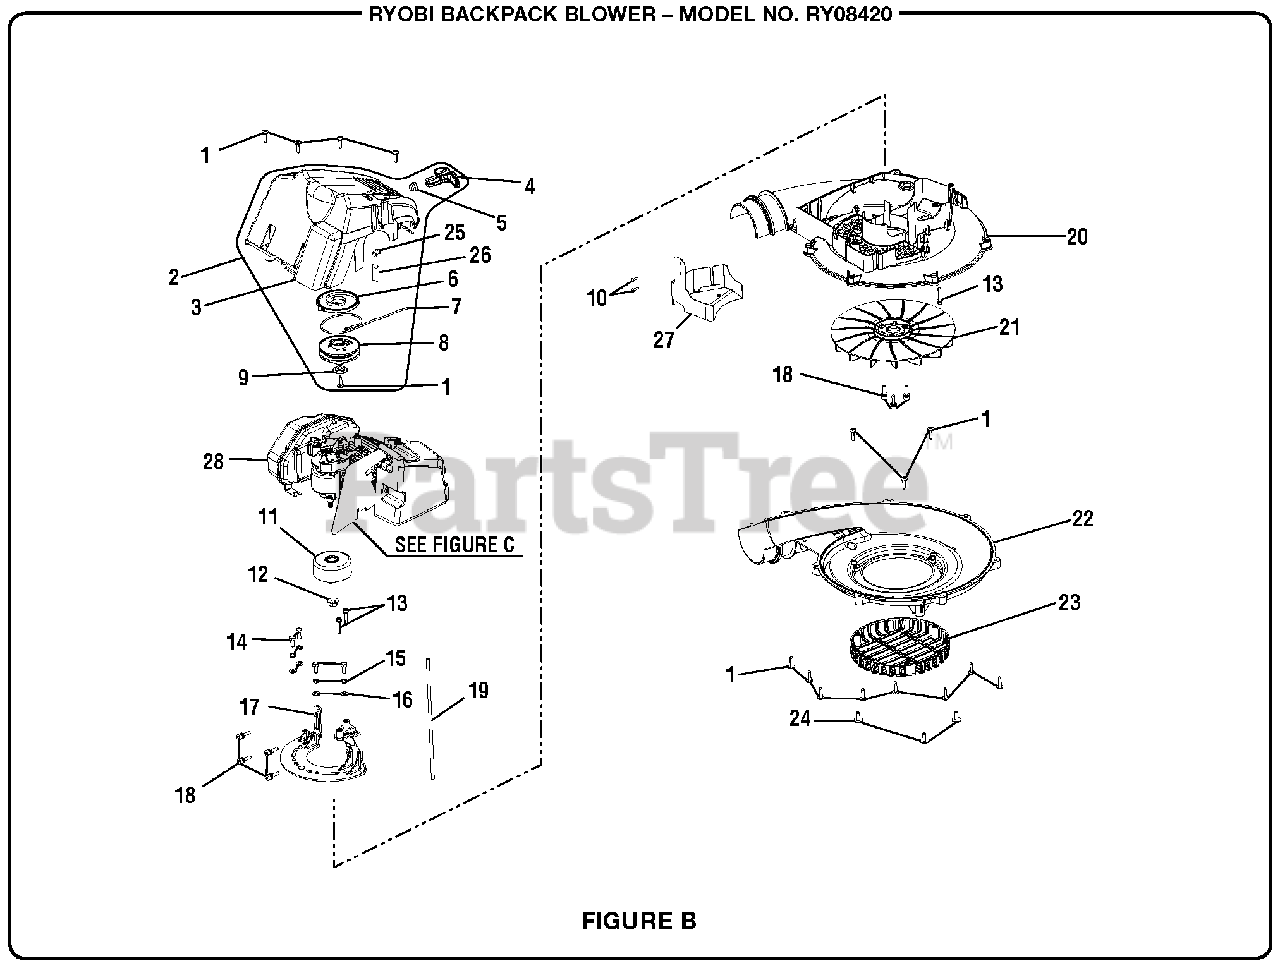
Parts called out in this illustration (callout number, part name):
1	Screw (10-14 x 19 mm, T-25 Torx)
2	Engine Cover w/Starter Assembly
3	Motor Cover
4	Starter Grip
6	Container Spring Assembly
7	Starter Rope
8	Solid Pulley
9	Starter Cap
12	Lock Nut (M8)
13	Screw (M5 x 25 mm, T-25 Torx)
14	Screw (M6 x 14 mm)
15	Spring Washer (ID6.4 x 1.6t)
16	Washer (OD12.9 x ID6.6 x 1.2t)
17	Engine Mount
18	Screw (M5 x 0.8 in., 20 Torx)
20	Inner Volute
22	Outer Volute
23	Outer Volute Cover
24	Screw (10-14 x 16 mm)
26	Eyelet Support
27	Outer Volute Duct
28	Power Head
